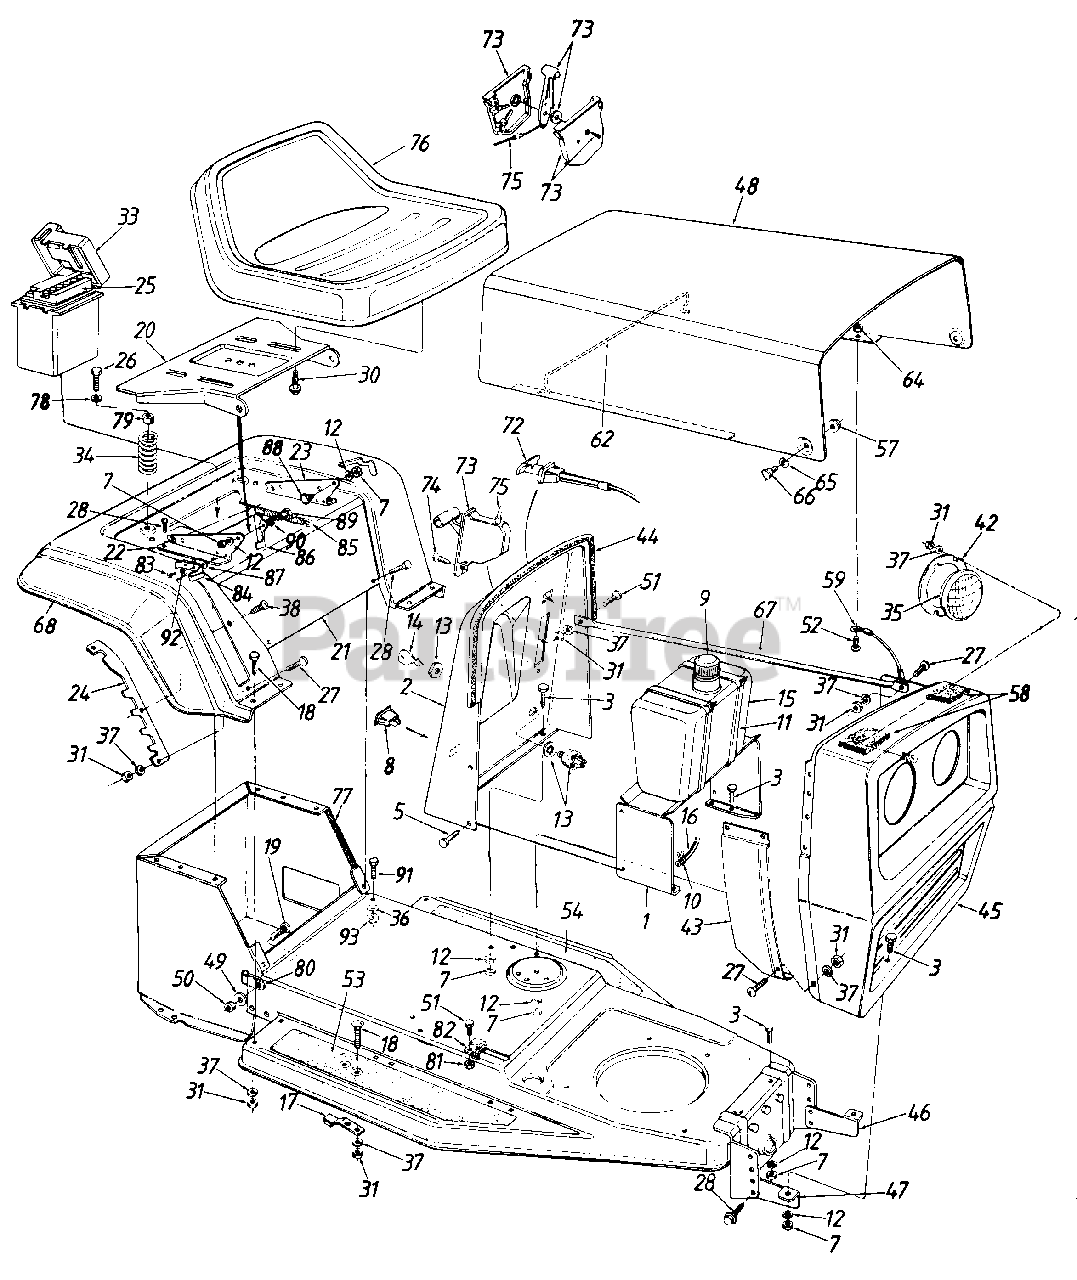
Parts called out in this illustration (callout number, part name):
1	Dash Panel Support Brkt.
5	Hex AB-Tap Scr. 1/4 X .62"
7	Hex Nut 5/16-18 Thd.
8	Light Switch
9	Gas Gauge
10	Hose Clamp
11	Cable Tie
12	L-Wash. 5/16" I.D.
13	Ignition Switch
14	Ignition Key
15	Fuel Tank
16	Gas Line
17	Blade Brake Ass'y.
18	Carriage Bolt 1/4-20 x .62"
19	Ribbed Neck Bolt 3/8-24 x .8"
20	Seat Pivot Brkt.
21	Rear Fender
22	Seat Hinge Support Brkt. R.H.
23	Seat Hinge Support Brkt. L.H.
24	Deck Lift Index Brkt.
25	Battery
26	Hex Self-Tap Screw 5/6-18 x 1.25" Lg.
27	Truss Mach. Scr. 1/4-20 X .75" Lg.
28	Hex AB-Tap Scr. 5/16 X .751 Lg.
30	Hex Self-Tap Scr. 3/8-16 x .75" Lg.
31	Hex Nut 1/4-20 Thd.
33	Battery Box w/Cover
34	Compression Spring
35	Headlight
36	Bell-Wash. 5/16" I.D.
37	L-Wash. 1/4" I.D.
38	Hex Wash. Hd. Tap Scr. #10 x .5" Lg.
42	Headlight Retainer
43	Side Panel R.H.
44	Trim Strip 31" Lg.
47	Grille Mtg. Brkt. R.H.
50	Hex L-Nut 3/8-24 Thd.
51	Hex Bolt 1/4-20 x .62" Lg.
52	Truss Mach. Scr. #10-24 x .5" Lg.
53	Foot Pad R.H.
54	Foot Pad L.H.
57	Lock Nut 1/4-28 Thd.
58	Foam Strip
59	Hood Stop
62	Hood Spring
64	Hex Sems Nut #10-24 Thd.
65	Spr. Wash. .39" I.D. x .62 O.D.
66	Shld. Bolt
67	Grille Support
68	Trim Strip 81" Lg.
72	Choke Control
73	Throttle Control Box
74	Truss AB-Tap Scr. #10 x .5"
75	Throttle Wire
76	Seat Assembly
77	Trim Strip 5" Lg.
78	Flat Wash. .344" I.D. x .88 O.D.
79	Bushing
80	Clamp
81	Hex L-Nut 1/4-20 Thd.
82	Clamp
83	Hex Tap Scr. #8 x 5" Lg.
84	Spring Switch
85	Ext. Spring 5.31" Lg.
86	Seat Lift Brkt.
87	Insulator Nut Plate
88	Shld. Bolt .437" Dia. x .162 Lg.
89	Shld. Bolt .437 Dia. x .268 Lg.
90	Spr. Wash. .445" I.D. x .75 O.D.
91	Hex Bolt 5/16-24 x 75" Lg.
92	Fiber Washer
93	Hex Nut 5/16-24 Thd.
